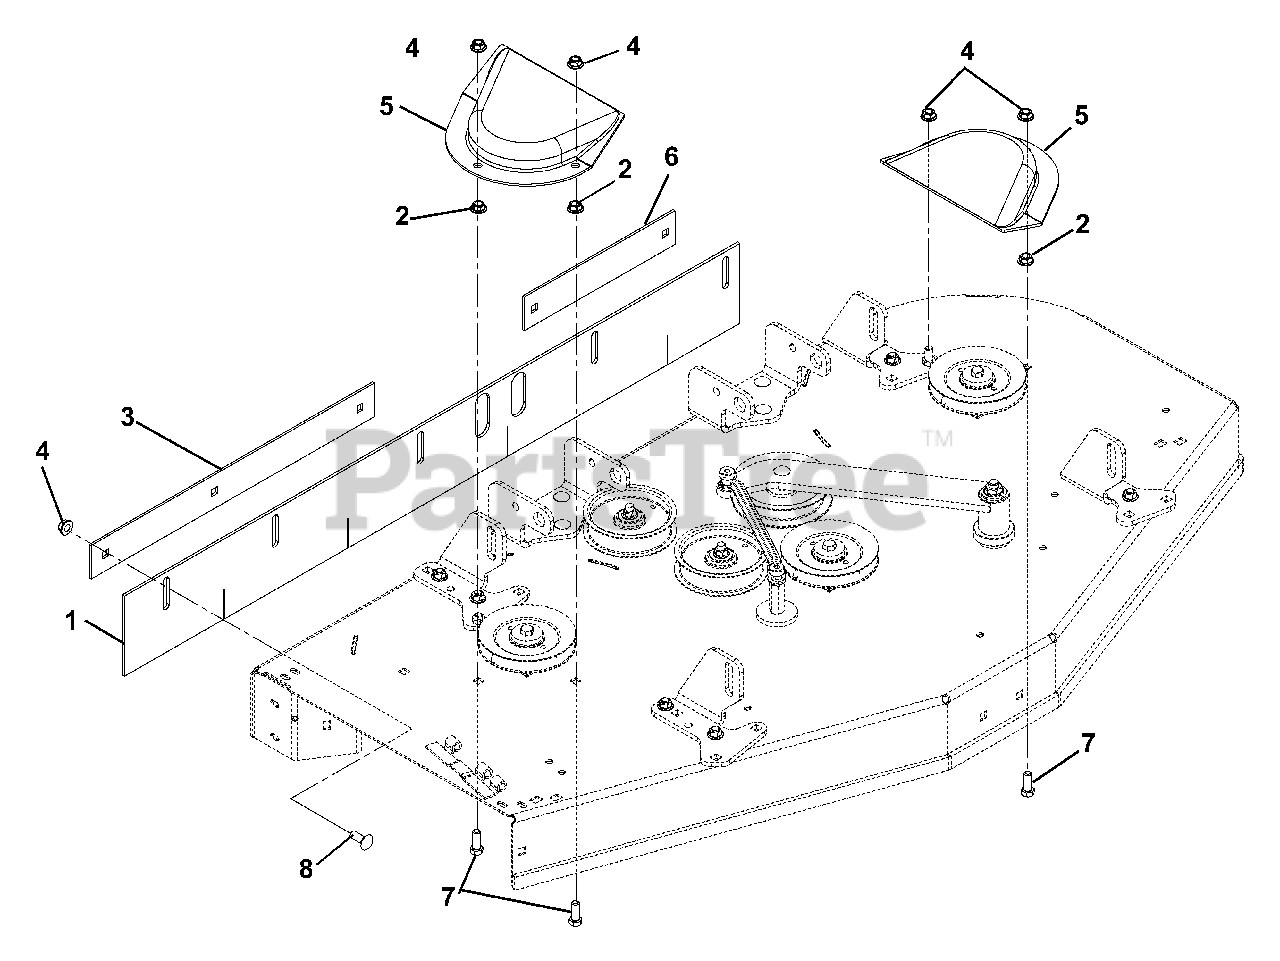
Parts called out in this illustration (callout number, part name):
1	Stripper, Rubber 48" (101)
1	Stripper, Rubber 44" (100)
2	Nut, Locking Top Flange .38-16
3	Bar, Retaining Stripper 44" (100)
3	Bar, Retaining Stripper 48" (101)
4	Nut, 3/8-16 Flange Nyloc
6	Bar, LH Retaining Stripper
7	Bolt, Hex .38-16 x 1.00
8	Bolt, Round Head Square Neck .38-16 x 1.00 Grade 5
